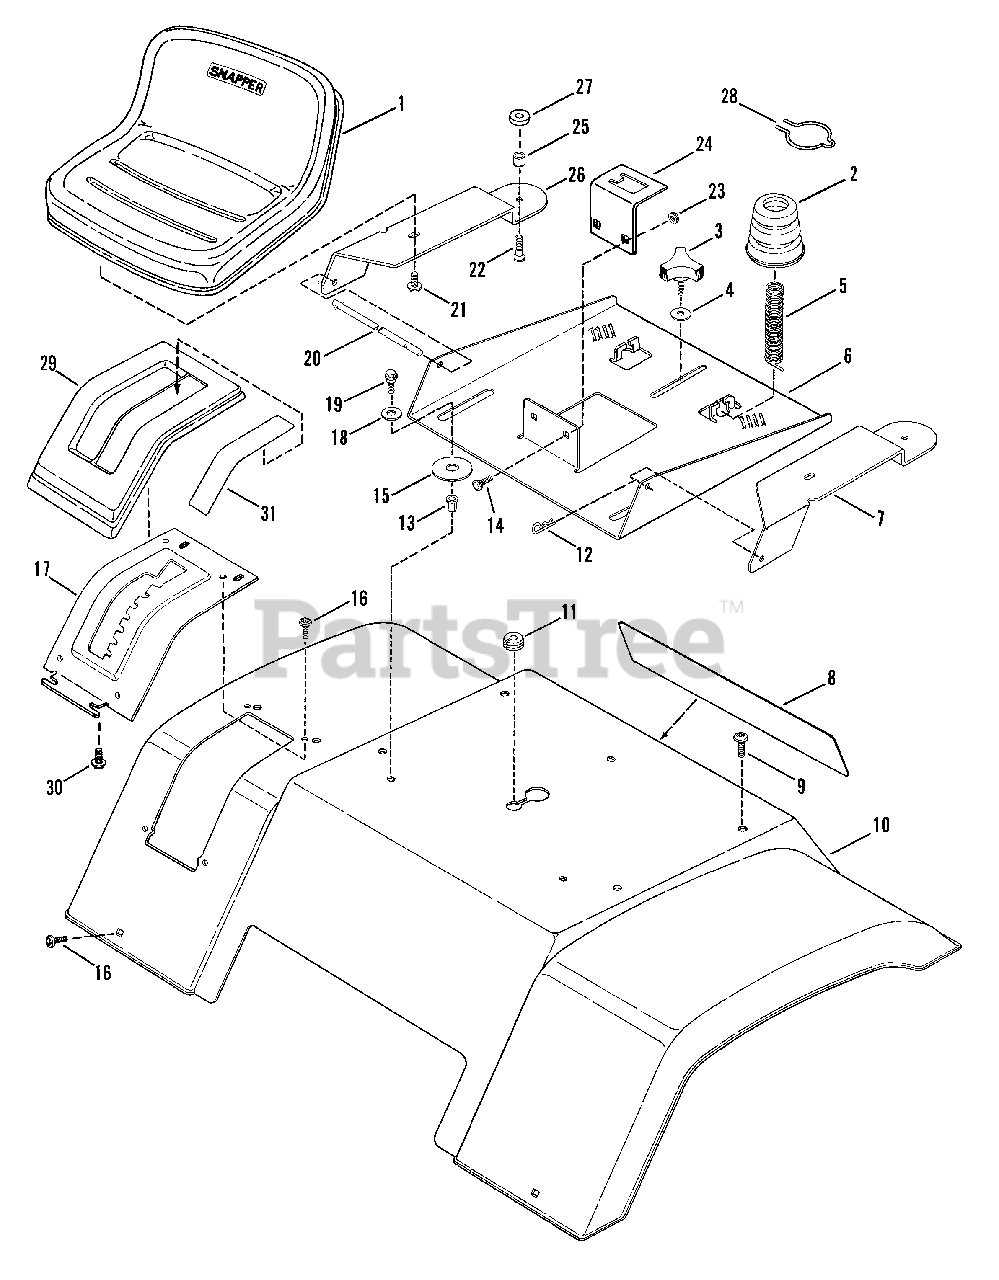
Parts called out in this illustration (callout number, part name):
1	SEAT, Operator's
2	CUSHION, Seat
3	KNOB, Seat Adjustment
4	WASHER
5	SPRING
6	SUPPORT, Seat
7	BRACKET, Seat Support, L.H.
8	DECAL, SNAPPER Molded Logo
9	SCREW, 5/16-18 x 7/8" Torx. Hd., S.T.
10	FENDER, Rear
11	GROMMET, 5/16 I.D. x 1" O.D. Split
12	PIN, Hair
13	RIV-NUT, 5/16-18
14	BOLT, 5/16-18 x 5/8" Short Neck Carriage
15	SPACER
16	SCREW, 1/4-20 x 5/8" Torx Hd., Self-Tapping
17	DETENT,Shift
19	SCREW, Shoulder, 5/16-18 x 3/4"
20	ROD, Seat Hinge
21	BOLT, 5/16-18 x 1/2" Hex Flange Lock
22	SCREW, 5/16c x 1" Flat Hd. Hex Recess
23	NUT, 5/16-18 Hex Flange Lock
24	BRACKET, Switch
25	SPACER,
26	BRACKET, Seat Support, R.H.
28	CLIP, Seat Bumper
29	COVER, Shift Detent
30	SCREW, #10-16 x 1/2" Self-Tapping
31	DECAL, Shift Cover
